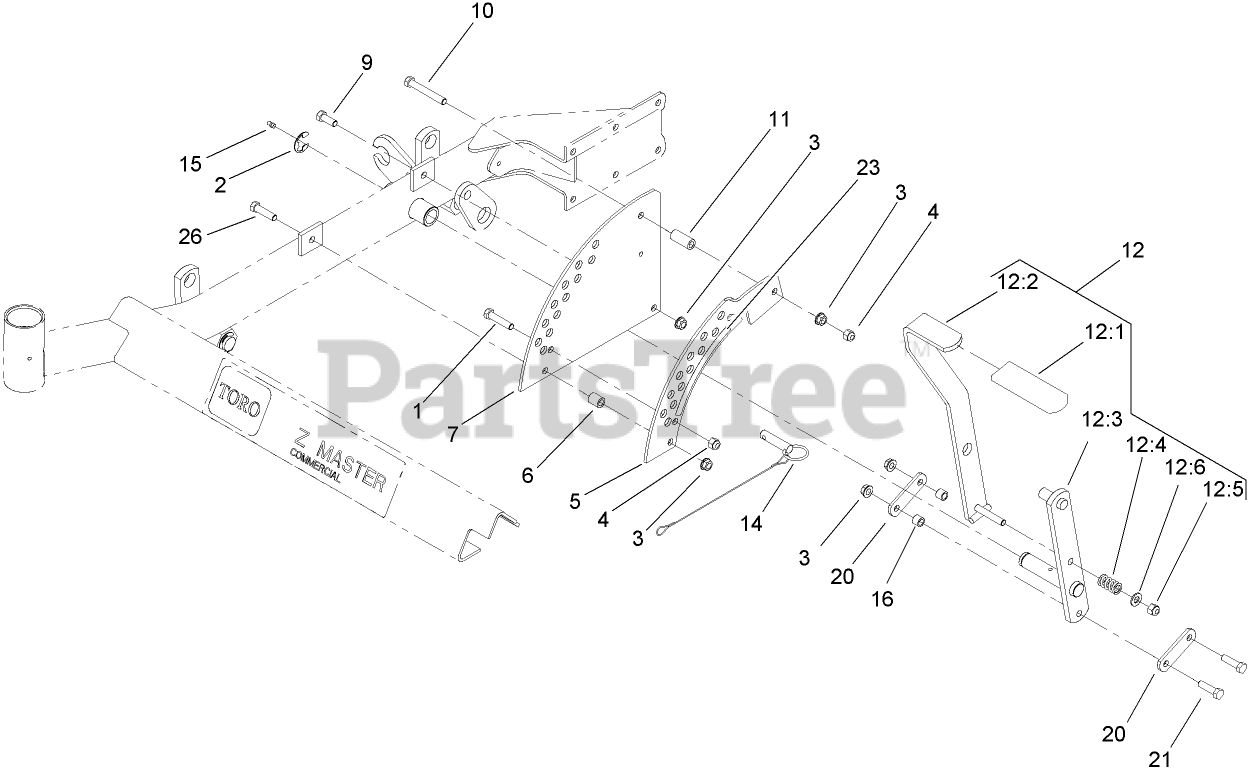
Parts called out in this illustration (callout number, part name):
1	SCREW-HH
2	RING-RETAINING, EXT
3	NUT-HHF, WHIZ
4	NUT-LOCK, NI
5	PLATE-LIFT, DECK
6	BUSHING-LEVER, LIFT
7	PLATE-LIFT, DECK
9	SCREW-HH
10	SCREW-HH
11	BUSHING-LEVER, LIFT
12	DECK LIFT HANDLE ASM
12:1	GRIP-LEVER, LIFT
12:2	HANDLE-LIFT
12:3	LIFT ARM ASM
12:4	SPRING-COMPRESSION
12:5	NUT-LOCK, NI
12:6	WASHER-FLAT
14	Hitch Pin ASM
15	FITTING-GREASE
16	Bushing
20	ARM-LIFT, DECK
21	SCREW-HH
23	DECAL-DECK HEIGHT, INNER
26	SCREW-HH
